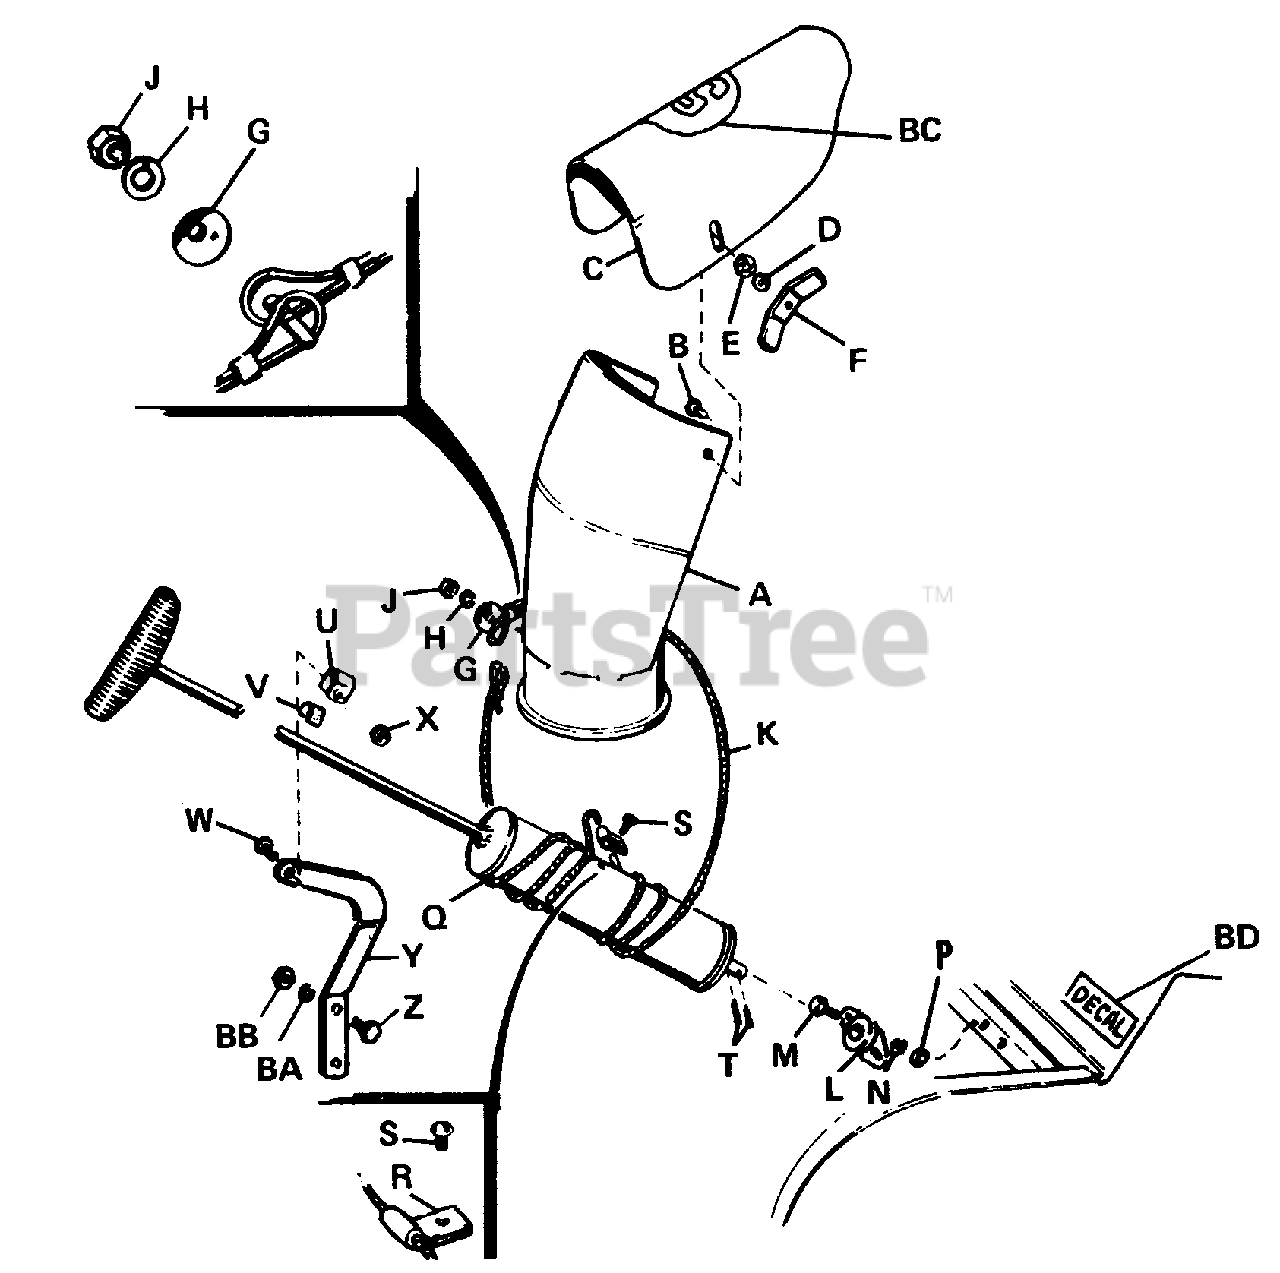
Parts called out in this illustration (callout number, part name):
A	Spout Assembly
B	Carriage Bolt, 5/16"-18 x 3/4"
C	Spout Extension
D	Washer, Plain 3/8"
E	Washer, Lock 3/8"
F	NUT, Wing, 5/16-18
G	Cup Washer
H	Wahser, Lock 5/16"
J	Nut, Hex Full 5/16"-18
K	Cable Assembly
M	Capscrew, Hex, 1/4"-20 x 5/8"
N	Washer, Lock 1/4"
P	Nut, Hex, Full 1/4"-20
Q	Tube Assembly, Spout Control
R	Clamp (For service only)
S	Self-Tapping Screw, 1/4"-20 x 3/8"
T	Cotter Pin, l/8' x 3/4"
V	Liner, Guide
W	Capscrew, Hex, 5/16"-18 x 1-1/2" lg.
X	Nut, Hex, Full, Lock, 5/16"-1
Y	Rod Guide Support
Z	Hex. Capscrew, 3/8"-16 x 1" lg.
BA	Lock Washer, 3/8"
BB	Hex. Nut, Full, 3/8"-16
BD	Decal Safety
